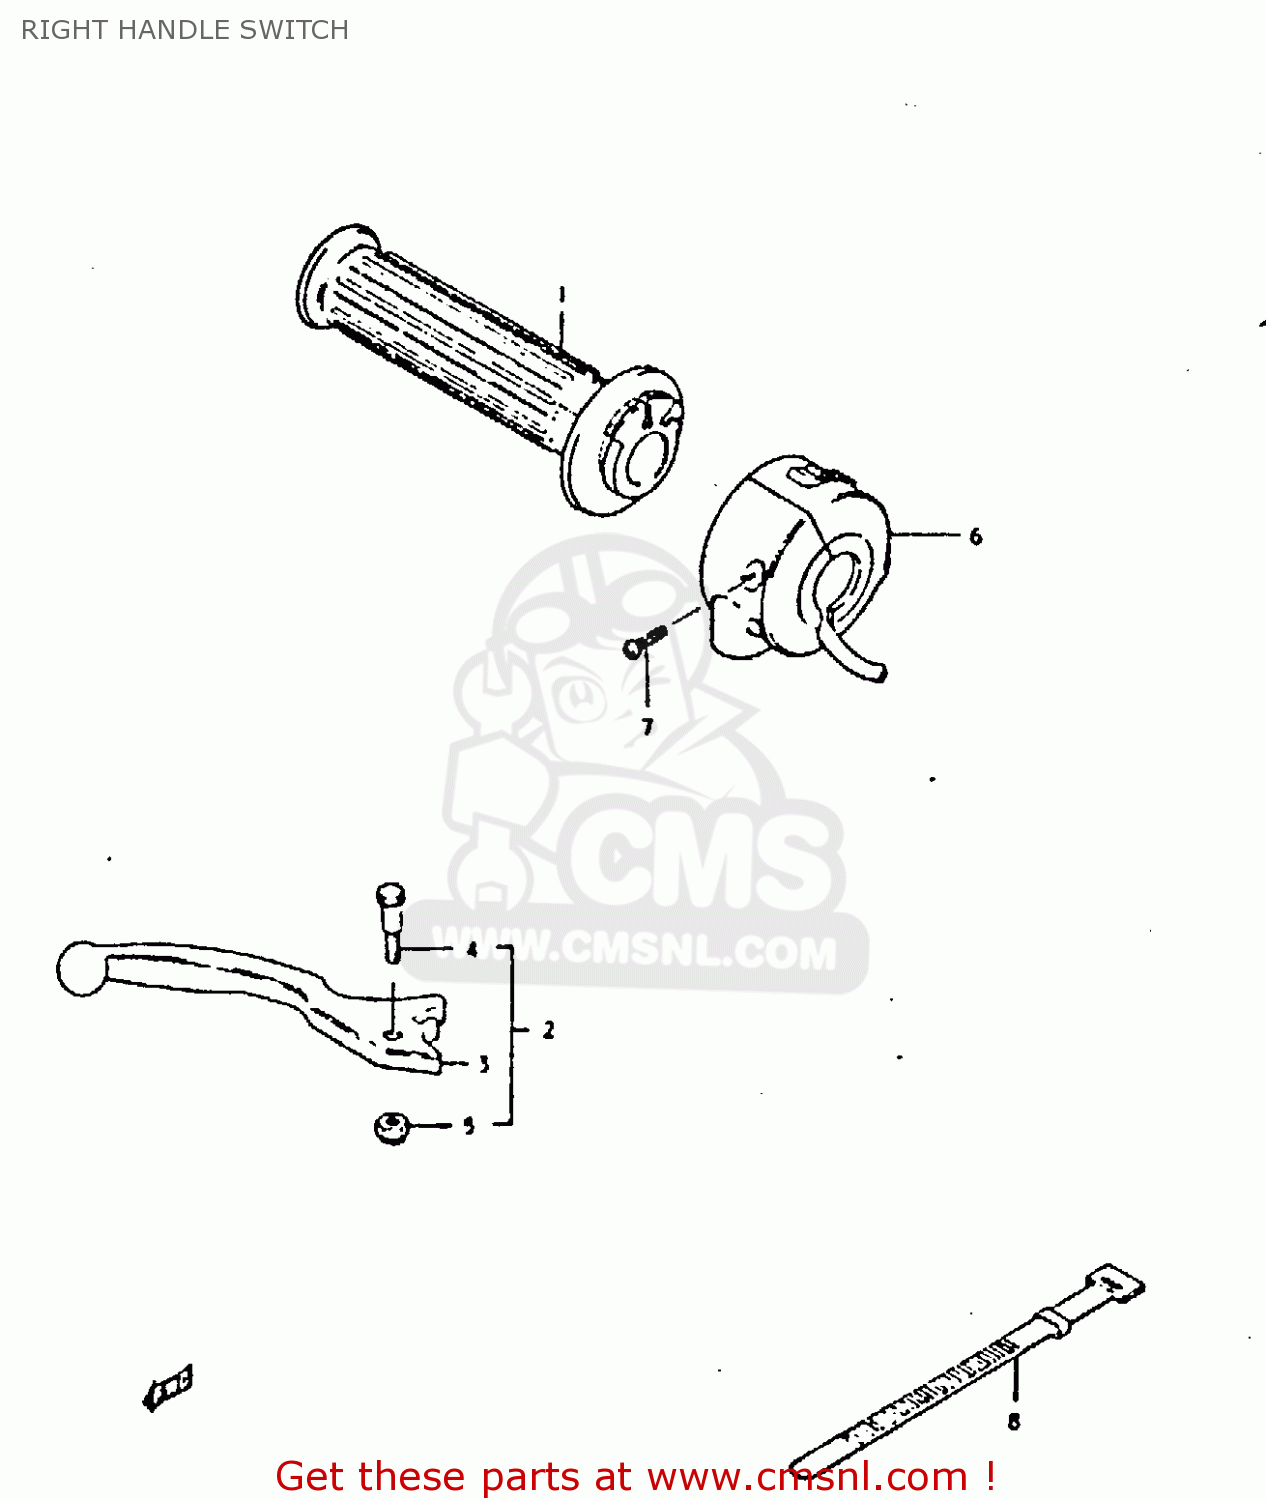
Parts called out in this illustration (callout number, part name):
1	GRIP,THROTTLE
2	LEVER ASSEMBLY,BRAKE
3	LEVER,BRAKE
4	BOLT
5	NUT 6MM
6	SWITCH ASSEMBLY,HANDLE,RIGHT
7	SCREW
8	CLAMP(L:120)
